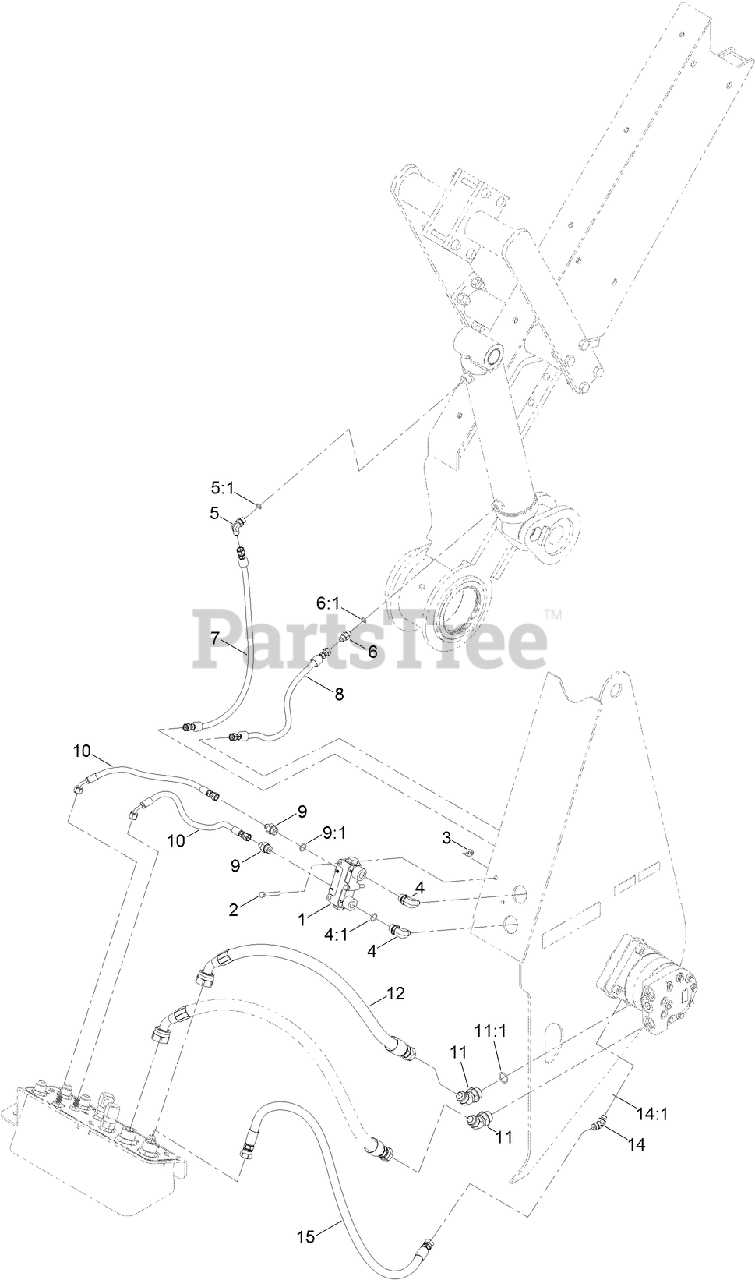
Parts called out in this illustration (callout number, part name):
1	HYD LOCKOUT VALVE ASM
2	SCREW-HH
3	NUT-HF
4	FITTING-ELBOW, 90 DEG
4:1	O-RING
5	FITTING-ELBOW, 90 DEG
5:1	O-RING
6	FITTING-STRAIGHT
6:1	O-RING
7	HOSE ASM
8	HOSE ASM
9	CONNECTOR
9:1	O-RING
10	HOSE ASM HYD
11	FITTING-JIC 37
11:1	O-RING
12	HOSE ASM
14	FITTING-ELBOW, 45
14:1	O-RING
15	HOSE ASM-HYD HP
